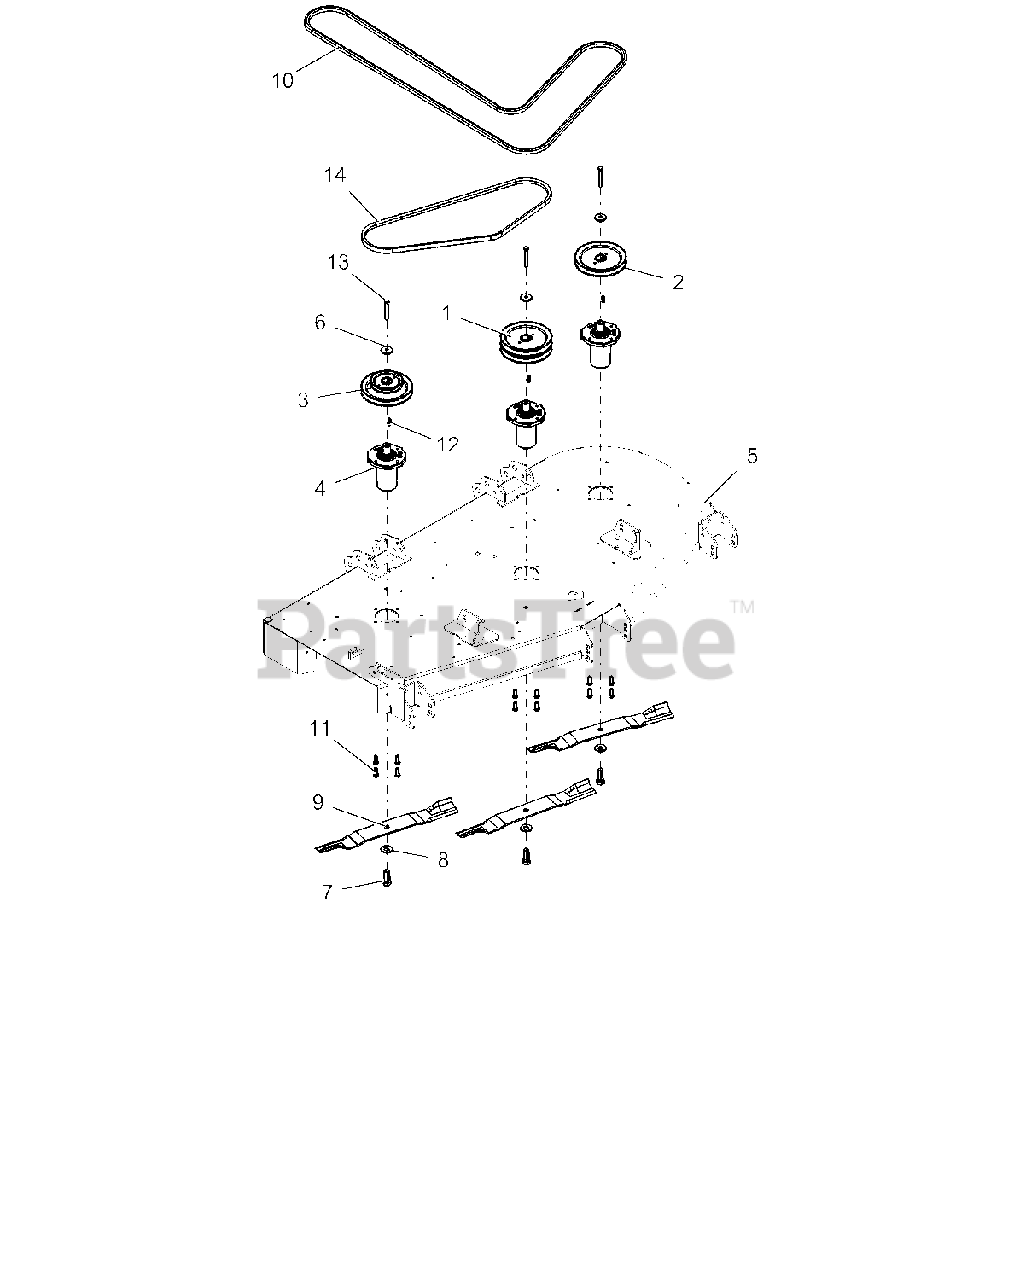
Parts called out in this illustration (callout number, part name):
1	PULLEY, DOUBLE-1"ID X 6.75"OD
2	PULLEY, V-1" ID X 6.75" OD
3	PULLEY, DBL-1"IDX6.75"&4.25"OD
4	ASM, MAINT FREE SPINDLE
5	KIT,DECK - 60" W/SAFETY DECALS
6	RETAINER, SHEAVE
7	BLT-HEX .62-18X1.75 GR8 YWZC
8	WSHR-BLVL .669X1.535X.138
9	BLADE, 20.5"
10	HEX BELT, BB-WRAPPED
11	BLT-HEX .38-16X1.0 GR8 YZ EP30
12	KEY, SQ .25X.25X1.00 RC 40-50
13	BLT-HEX .38-16X2.75 GR8 YWZC
14	V-BELT, B-COGGED
